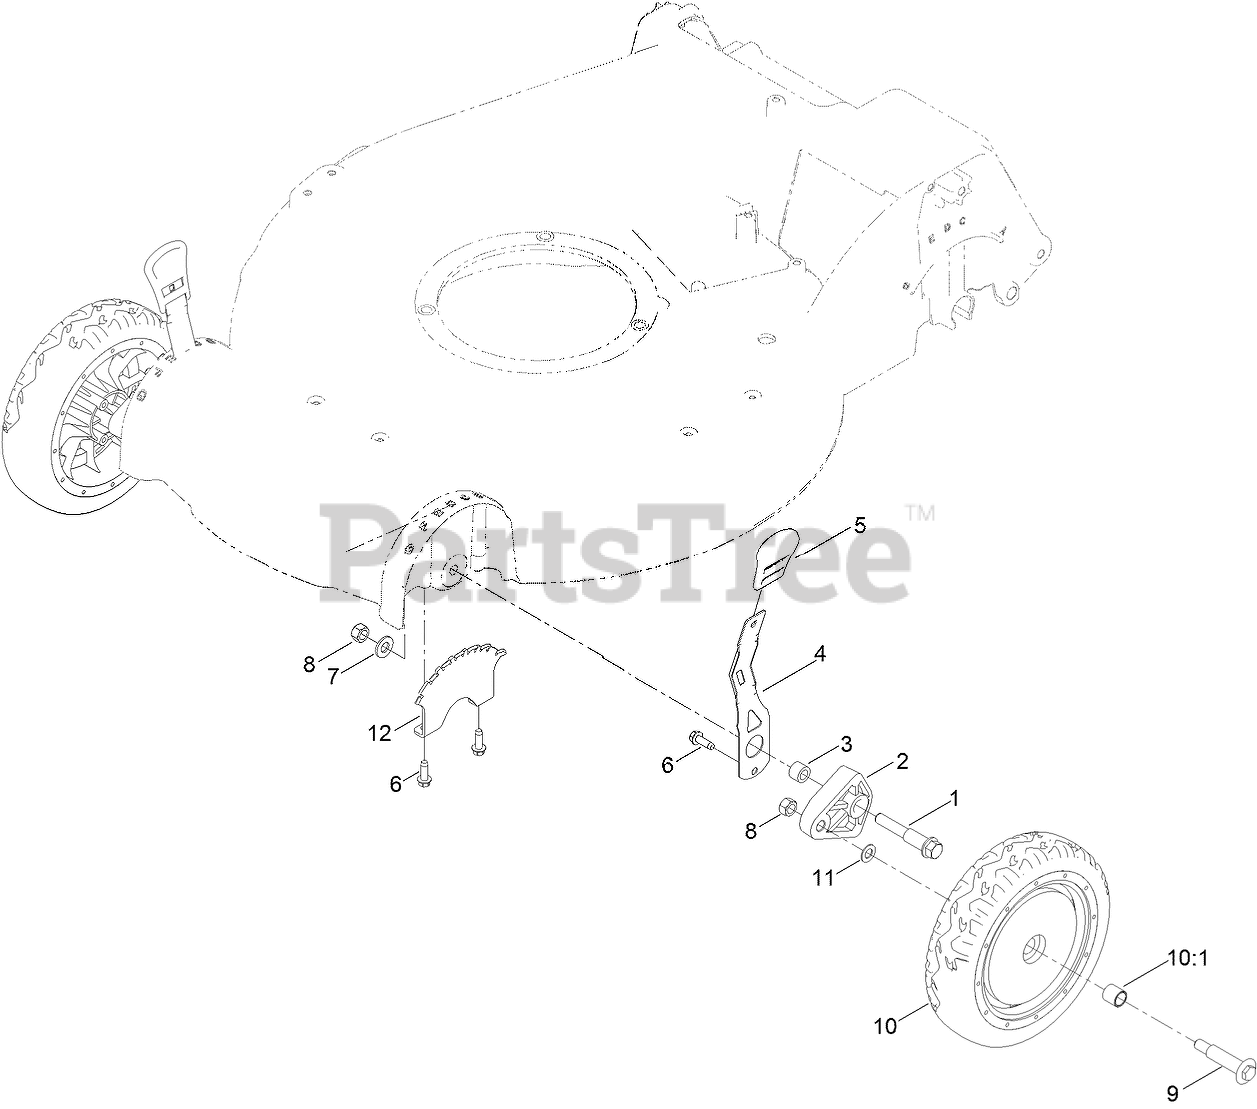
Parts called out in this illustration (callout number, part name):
1	SCREW-SHOULDER
2	ARM-PIVOT
3	SPACER-WHEEL
4	ARM-SPRING
5	KNOB-HOC
6	SCREW-HWHTF
7	WASHER-FLAT
8	LOCKNUT
9	BOLT-SHOULDER
10	8 INCH WHEEL ASM
10:1	BUSHING
11	WASHER
12	PLATE-HOC
